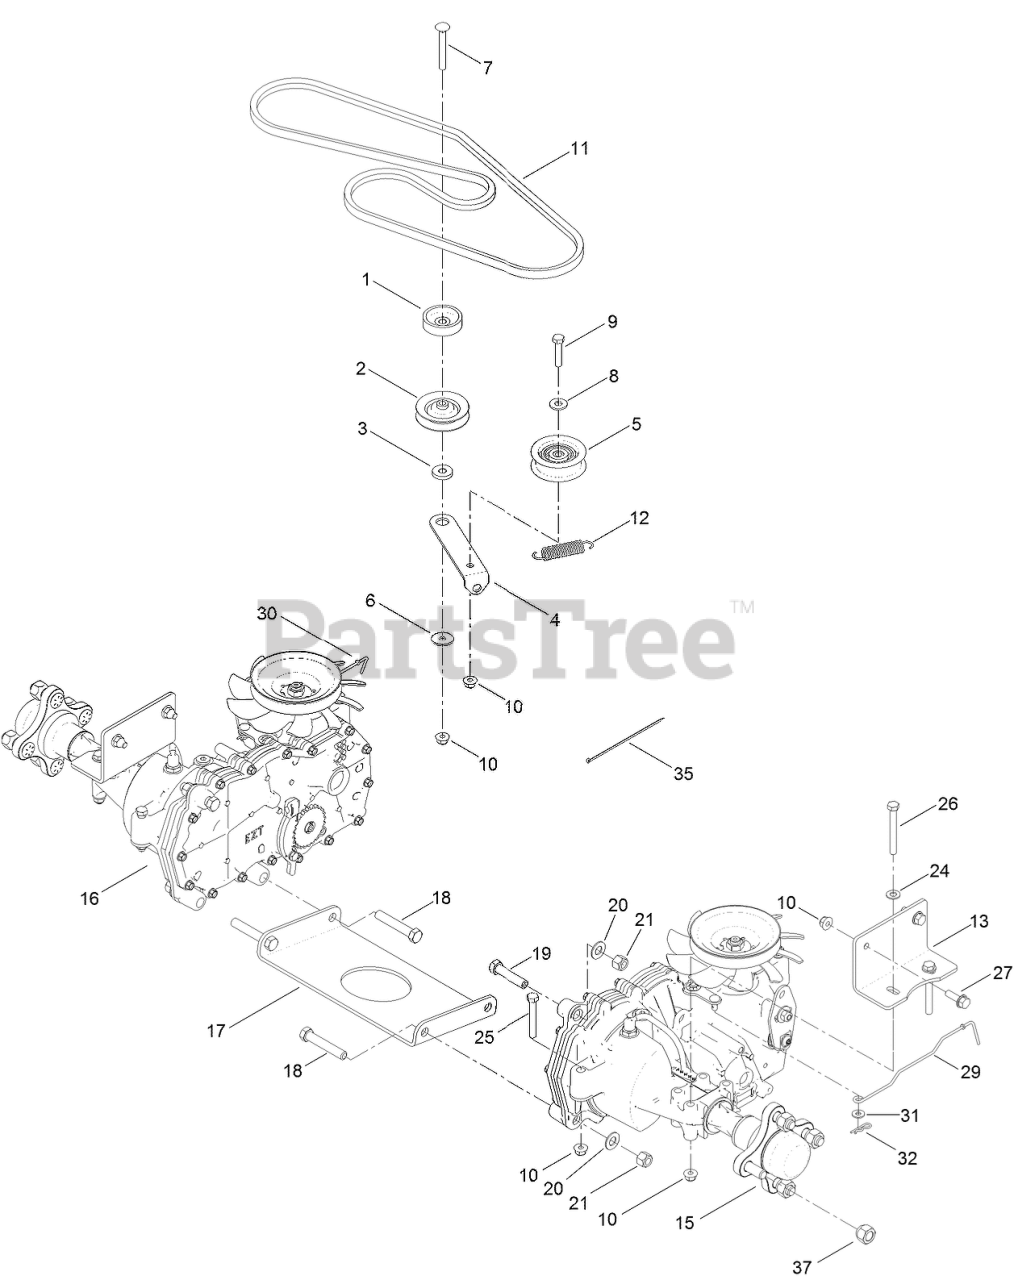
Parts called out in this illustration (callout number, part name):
1	SPACER
2	PULLEY-IDLER
3	SPACER-ARM, IDLER
4	ARM-IDLER
5	PULLEY-IDLER
6	WASHER-PIVOT
7	SCREW-CARR
8	WASHER-FLAT
9	SCREW-HH
10	NUT-HF, NI
11	V-BELT
12	SPRING-RETURN, PEDAL
13	MOUNT-HYDRO
15	LH HYDRO TRANSAXLE ASM
16	RH HYDRO TRANSAXLE ASM
17	PLATE-CROSS, HYDRO
18	SCREW-HH
19	SCREW-HH
20	WASHER-FLAT
21	NUT-LOCK, NI
24	WASHER-PLAIN
25	SCREW-HH
26	SCREW-HH
27	SCREW-HHF
29	ROD-BYPASS, LH
30	ROD-BYPASS, RH
31	WASHER
32	PIN-COTTER
35	TIE-CABLE
37	NUT-LUG
